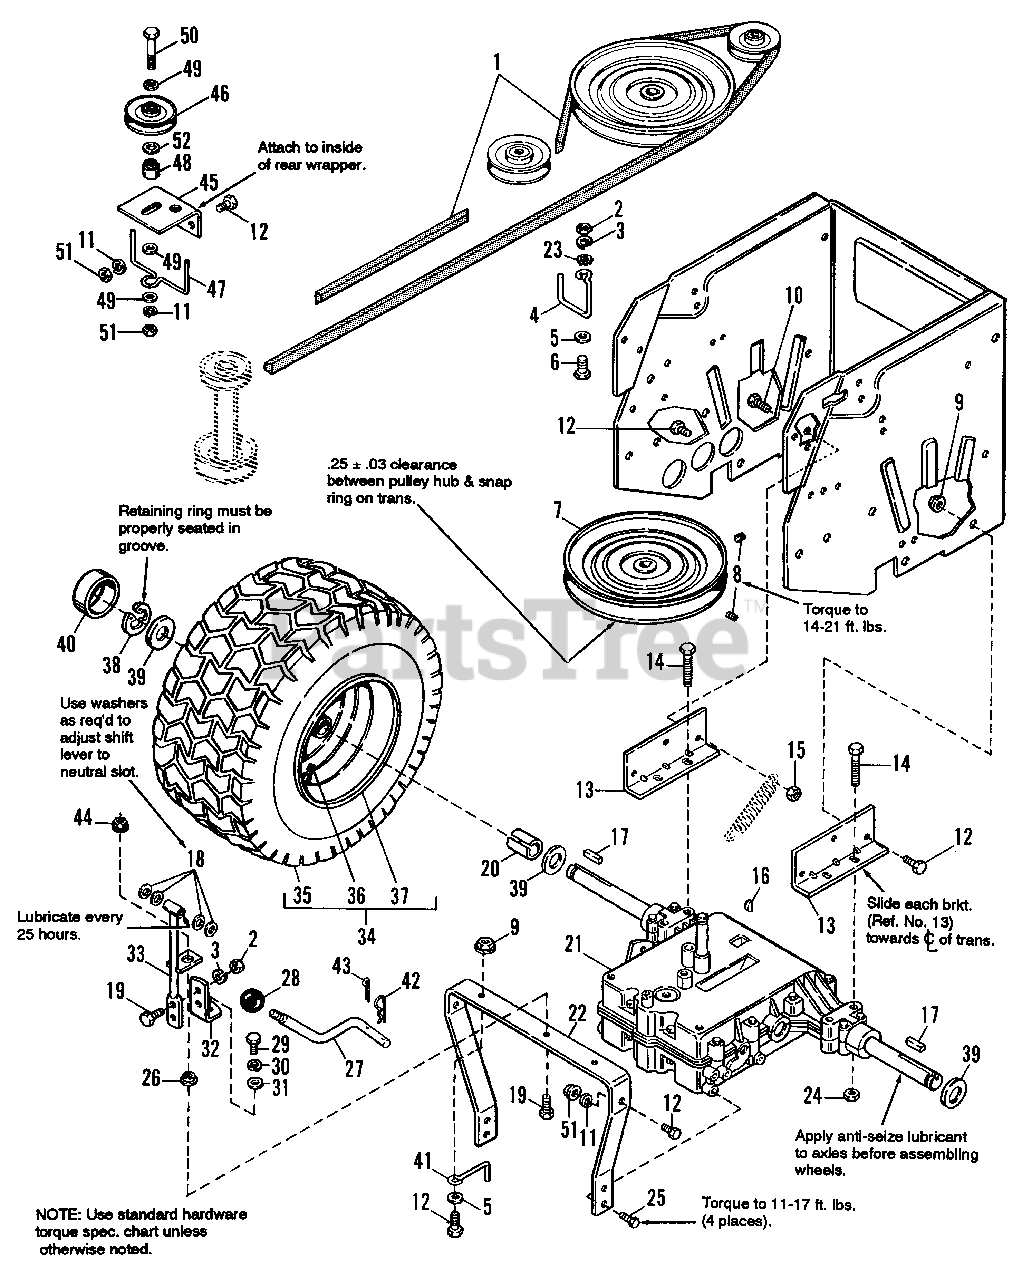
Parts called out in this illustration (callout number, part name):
2	NUT, Hex, 5/16-18
3	LOCKWASHER, 5/16
5	WASHER, 11/32
6	CAPSCREW, Hex, 5/16-18 x 1
7	PULLEY ASSY., Transmission
8	SETSCREW, 5/16-18 x 5/8
9	LOCKNUT, Hex, Flange, 3/8-16
10	CAPSCREW, Hex, 3/8-16 x 1-1/4
11	LOCKWASHER, 3/8
12	CAPSCREW, Hex 3/8-16 x 1
13	SUPPORT, Transmission, Rear
14	CAPSCREW, Hex, 5/16-18 x 2-1/4
15	LOCKNUT, Hex, 3/8-16
16	KEY, Woodruff, #9
17	KEY, 3/16 x 3/16 x 1-1/2
18	WASHER, Rev. Pinion
19	CAPSCREW, Hex, 5/16-18 x 1-1/4
21	TRANSAXLE, 5 Speed, Peerless
22	SUPPORT, Transmission, Front
23	LOCKWASHER, Ext.
24	LOCKNUT, 5/16-18
25	SCREW, Taptite, 5/16-18 x 5/8
26	SPACER, Special
27	ROD, Shit
28	KNOB, Ball, Shift
29	CAPSCREW, Hex, 1/4-28 x 5/8
30	LOCKWASHER, 1/4
31	WASHER, Plain, 9/32
32	LINK, Shift, Lower
33	SHIFT LINK ASSY., Upper
34	WHEEL & TIRE ASSY., 18 x 8.50-8 (Turf Saver tire)
35	TIRE (Carlisle) 18 x 8.50-8 (Turf Saver tire)
36	VALVE STEM & CAP
37	WHEEL ASSY.
40	CAP, Hub, Threaded
42	PIN, Quick
43	PIN, Cotter
44	NUT, Hex Flange Hd., 5/16-18
45	BRACKET, Pulley
46	PULLEY, Idler, "V"
49	WASHER
50	CAPSCREW, 3/8-16 x 2-3/4
51	NUT, Hex, 3/8-16
52	WASHER, 13/32
